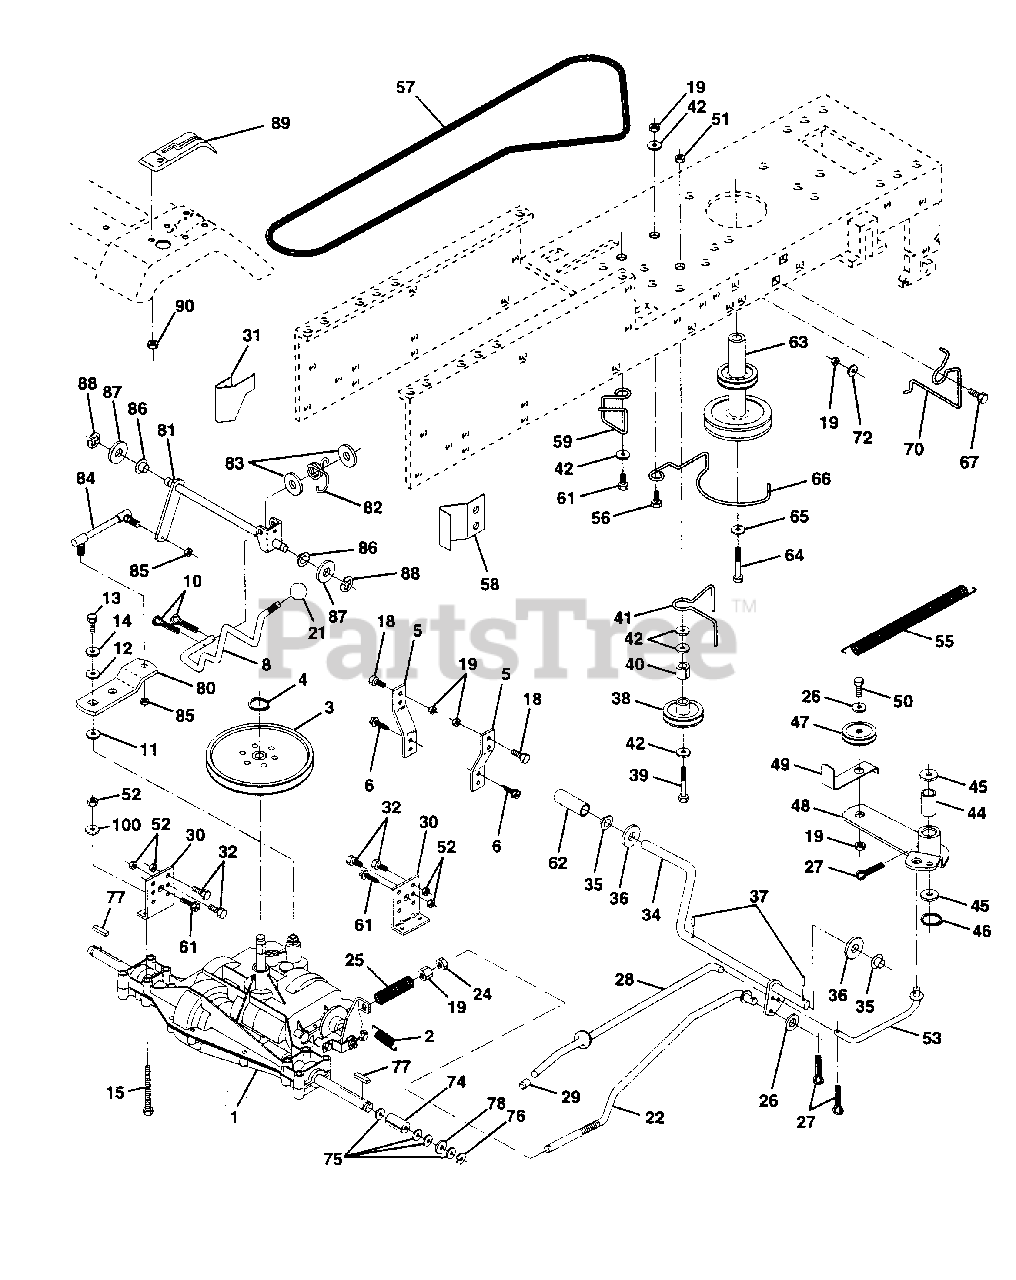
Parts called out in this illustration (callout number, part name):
1	Transaxle 6sp Model No. 4360-79
2	Spring Return Brake
3	Pulley Transaxle 18" tires
4	Ring Retainer # 5100-62
5	Strap Torque 30 Degrees
6	Screw Thdrol 5/16-18 X 3/4 TYT
10	Pin Cotter 1/8 X 1 Cad
11	Washer Plate Shf 388 Sq Hole
12	Washer 9/32 X 3/4 X 10 Ga
13	Bolt 1/4-28unf Gr8 w/Patch
14	Washer Lock Hvy Helical 1/4
15	Bolt Fin Hex 5/16 - 18 UNC x 2.75
18	Bolt Fin Hex 3/8-16unc X 1 Gr. 5
19	Nut Hex Lock W/Ins 3/8-16 Unc
21	Knob Duckhead 1/2-13 UNC
22	Rod Brake Blk Zinc 27 326
24	Nut Hex Jam 3/8-16 Unc
25	Spring Rod Brake 2 00 Zinc
26	Washer 13/32 X 13/16 X 16 Ga
27	Pin Cotter 1/8 X 3/4 Cad
28	Rod Brake Parking LT/YT
29	Cap Brake Parking Black
30	Bracket Mtg Transaxle
31	Keeper Belt LH LT 14 Ga
32	Bolt Hex Hd 5/16-18unc X 3/4
34	Shaft Asm Pedal Foot
35	Bearing Nylon Blk 629 Id
36	Washer 21/32 X 1 X 16 Ga
37	Pin Roll 3/16 X 1"
38	Pulley Idler Flat
39	Bolt Fin Hex 3/8-16unc X 2-3/4
40	Spacer Split 395 X 59 Bzp
41	Keeper Belt Retainer
42	Washer 13/32 X 13/16 X 12 Ga
44	Bearing Nyl 503 X 628 X 1 25
45	Washer Hardened
46	Ring Klip #t5304-50
47	Pulley Idler V Groove Plastic
48	Bellcrank Asm Clutch
49	Retainer Belt Style Spring
50	Bolt Hex Hd 3/8-16unc X 1-1/2
51	Nut Crownlock 3/8-16 Unc
52	Nut Crownlock 5/16-18 UNC
53	Link Clutch 7 66
55	Spring Return Clutch 6 75
56	Bolt Fin Hex 3/8-16 UNC x 1-1/4
57	V-Belt Ground Drive 95 25 42"
58	Keeper Belt RH LT Pnt/zinc 16g
59	Keeper Belt Chassis Span Ctr
61	Screw Thdrol 3/8-16x3/4 Ty-tt
62	Cover Pedal Blk Round
63	Engine Pulley
64	Bolt Hex 7/16-20x4 Gr 5
65	Washer Lock Hvy Hlcl Spr. 7/16
66	Keeper Belt Engine LH LT
67	Bolt Fin Hex 3/8-16 UNC x 1
70	Guide Belt Mower Drive RH
72	Washer 13/32 X 1-1/4 X 12 Ga
75	Washer 25/32 X 1 1/4 X 16 Ga.
76	E-ring #5133-75
77	Key Square 2 0 X 1845/ 1865
78	Washer 25/32 X 1-5/8 X 16 Ga.
80	Arm Shift Transaxle
81	Shaft Asm. Cross 18" + 42" Deck
82	Spring Torsion T/A
83	Washer 17/32 x 3/4 x 16 Ga.
84	Rod Shift Adj. Tie
85	Nut Nylock 1/4-28
86	Bushing Rod Strg. 629/632 Id
87	Washer 21/32 x 1 - 1/4 x 16 Ga.
88	Ring Klip #5304 - 62
89	Console Shift 6 st LT
90	Nut Self-thd Wsh-hd 1/4 Zinc
100	Washer 11/32 x 3/4 x 16 Ga.
